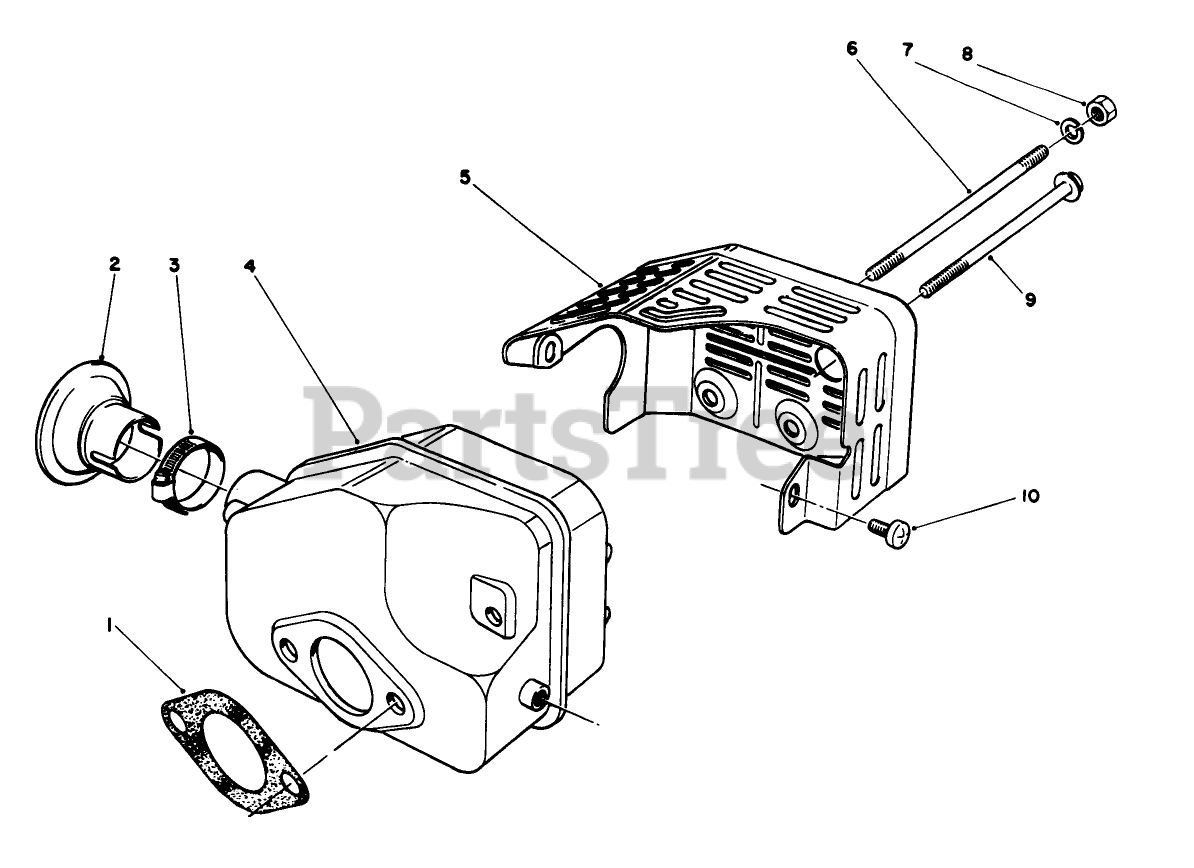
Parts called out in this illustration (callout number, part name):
1	GASKET
3	Clamp
4	MUFFLER
5	COVER-MUFFLER
7	WASHER-LOCK
10	SCREW
